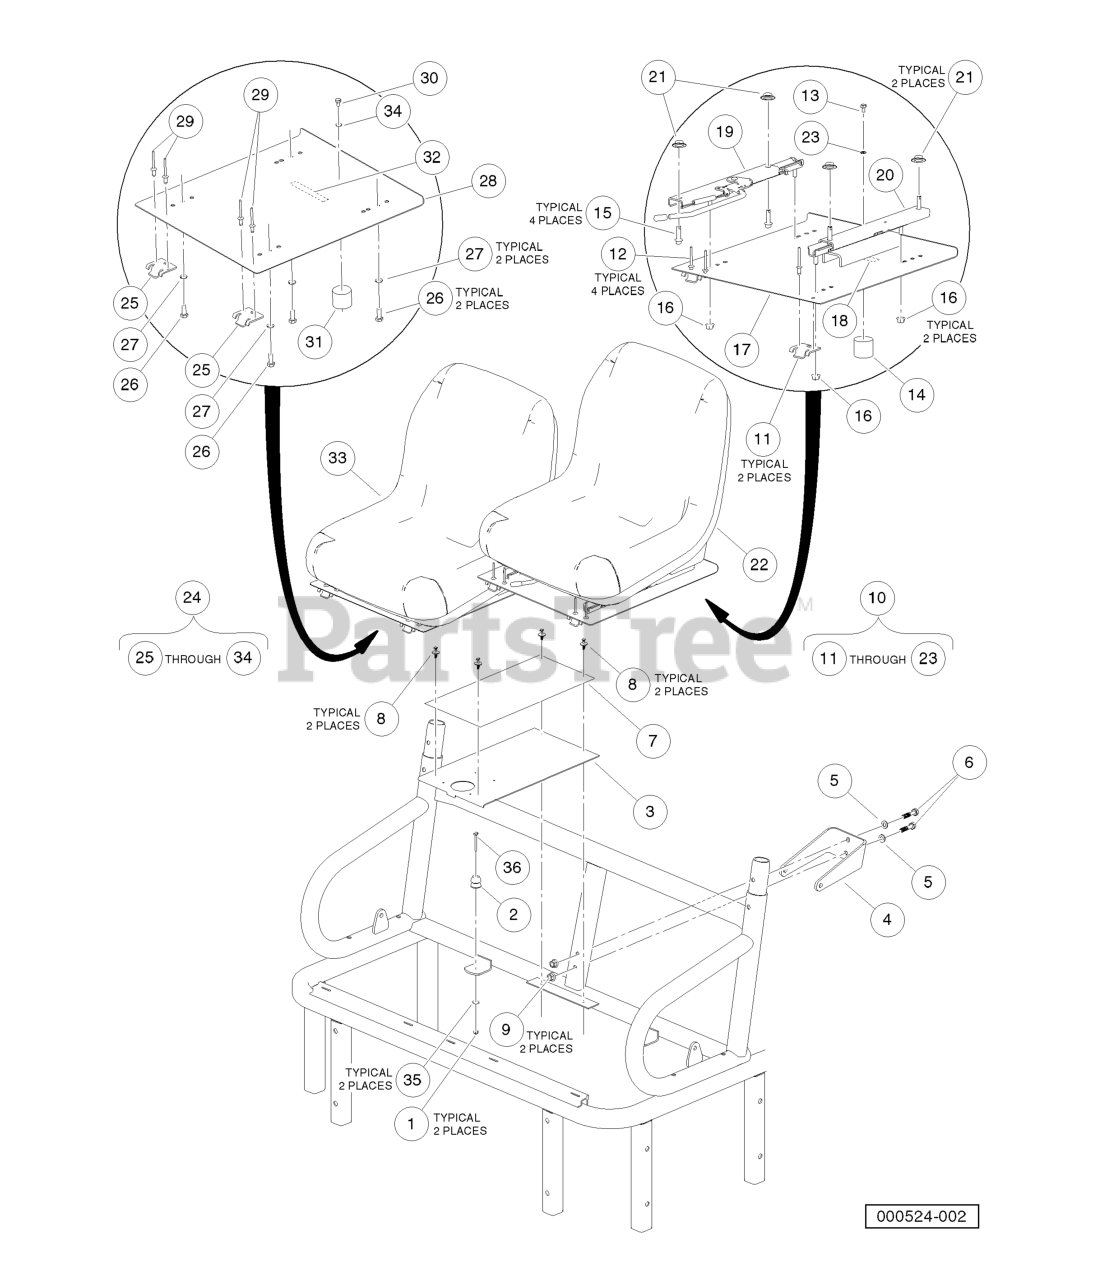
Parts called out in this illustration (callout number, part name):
1	LOCKNUT, M6-1.00 NYLON INSERT
2	SEAT HOLDER BASE
3	PAN, CENTER, CLOSEOUT
4	BRKT, SEATBELT, BOLT-ON
5	WASHER, HARD, M10, ZN-NI/BLK
6	BOLT, M10 X 45, ZN-NI/BLK
7	COVER, CENTER CONSOLE
8	SCREW, TUFLOK PANEL, 1/4
9	NUT, FLANGED, M10 X 1.5, BLACK
10	Asm, Bracket Seat, Adj, Blk
11	HINGE PLATE
12	RIVET, 1/4 X .438 BLIND
13	SCREW, 6M-1.00 X 10MM HEX HEAD
14	SEAT HOLDER CUP
15	BOLT - FLANGED HD, M8 X 30.0
16	NUT FLG, M8 X 1.25 MECH DEF
17	PAN, SEAT, DRIVER ASM
18	DECAL, WARNING HOT SURFACE
19	ADJUSTER, FORE/AFT
20	ADJUSTER, SLIDER
21	WASHER, BELL
22	SEAT, BUCKET, BLACK
23	LOCKWASHER, 1/4 HELICAL SPLIT
24	Asm, Bracket Seat, Passenger, Blk
25	HINGE PLATE
26	SCREW, M8-125 X 22 HEX GR.8.8
28	PAN, SEAT - PASSENGER
29	RIVET, 1/4 X .438 BLIND
30	SCREW, 6M-1.00 X 10MM HEX HEAD
31	SEAT HOLDER CUP
32	DECAL, WARNING HOT SURFACE
33	SEAT, BUCKET, BLACK
34	LOCKWASHER, 1/4 HELICAL SPLIT
35	WASHER 1/4 FLAT
36	BOLT, M6 X 1 X 45
